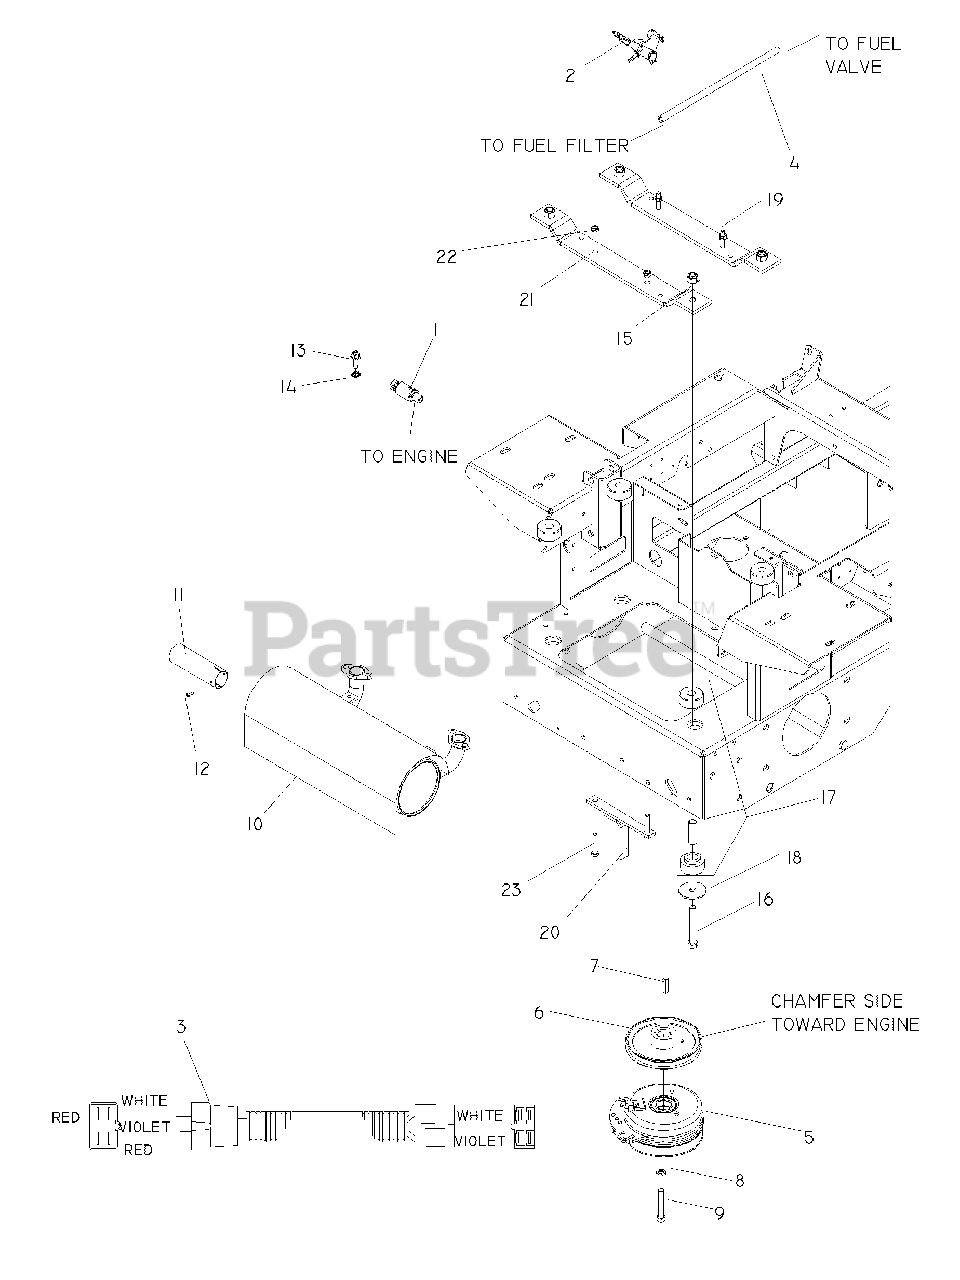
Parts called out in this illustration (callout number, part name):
1	OIL DRAIN FITTING
2	CHOKE CABLE
3	KOH PIGTAIL
4	FUEL LINE 13"
5	ELECTRIC CLUTCH W/CABLE
7	KEY, 1/4 SQ X 1 1/4
8	WASHER 7/16 LOCK
9	BOLT 7/16F X 2 1/2
10	MUFFLER
11	TUBE, EXTENSION, MUFFLER
12	SCR #8 X 1/2 PHIL HD DRILL BLK
13	BOLT 3/8-16 X 1.0
14	WASHER 3/8 EXT STAR ZD
15	NUT 1/2-13 HEX NYLOC ZD
16	HCS 1/2C X 3 1/4
17	ISOLATORS
18	ISOLATOR WASHER
19	ENGINE MOUNT
20	CLUTCH TIE DOWN
21	STRAP, ISO, REAR
22	NUT 5/16C CENTERLOCK
23	HCS 5/16-18 X 1-3/4 SERATED
